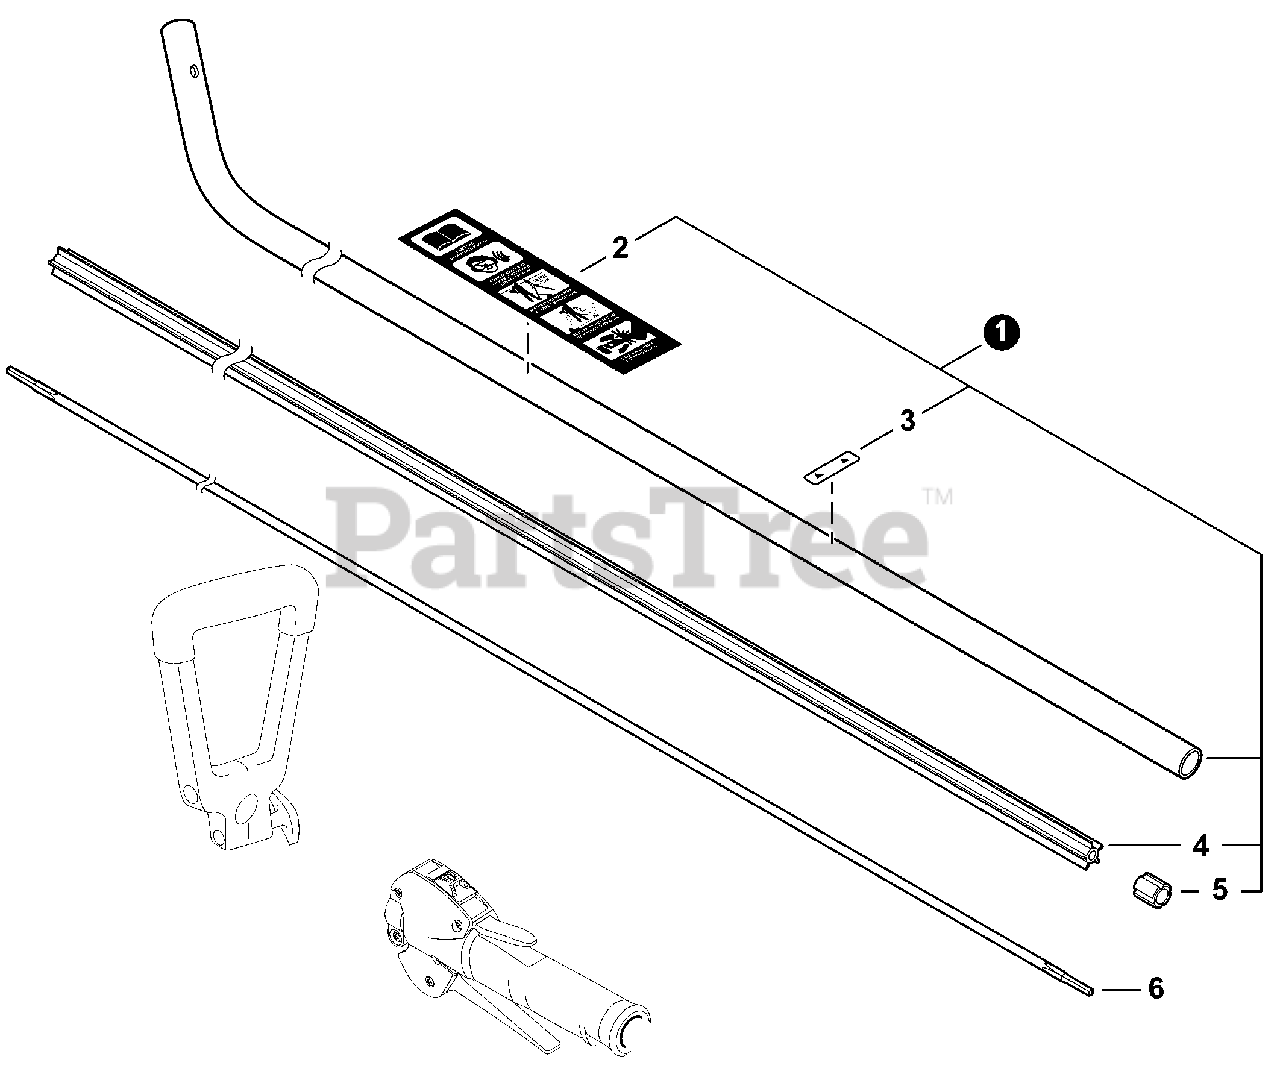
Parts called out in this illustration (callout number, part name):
1	MAIN PIPE ASSY
2	LABEL, CAUTION
3	LABEL - ALIGNMENT
4	LINER, FLEXIBLE 21.6×1420
6	DRIVESHAFT - FLEXIBLE
